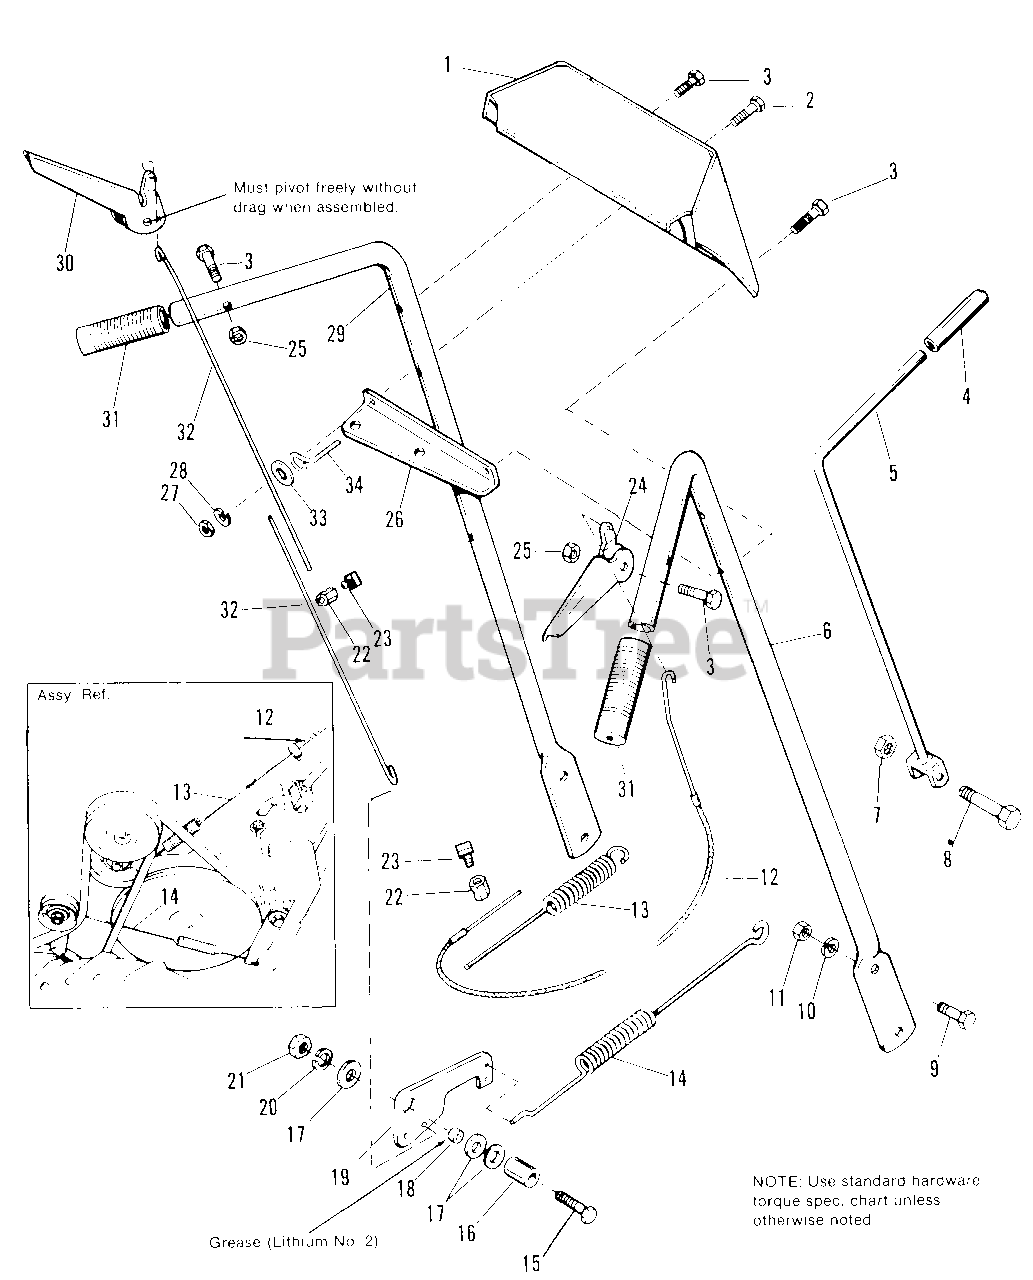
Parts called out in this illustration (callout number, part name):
1	HOUSING ASSY.
2	CAPSCREW, Hex Hd., 1/4-20 x 1-3/4
3	CAPSCREW, Hex Hd., 1/4-20 x 1-1/2
4	GRIP, Handle
5	ROD ASSY., Shift
6	HANDLE, R.H.
7	LOCKNUT, Hex, 5/16-18
8	CAPSCREW, Hex Hd., 5/16-18 x 2
9	CAPSCREW, Hex Hd., 5/16-18 x 7/8
10	LOCKWASHER, 5/16
11	NUT, Hex, Full, 5/16-18
12	CABLE & WIRE ASSY.
14	SPRING, Pivot Arm
15	CAPSCREW, Hex Hd., 7/16-14 x 2-3/4
17	WASHER, Plain, 3/8
19	ARM, Pivot
20	LOCKWASHER, 7/16
21	NUT, Hex, Full, 7/16-14
22	CLAMP, Wire
23	SETSCREW, #10-24 x 5/8
24	GRIP, Clutch, R.H.
25	LOCKNUT, Hex, 1/4-20
26	GUIDE, Rod
27	NUT, Hex, Full, 1/4-20
28	LOCKWASHER, 1/4
29	HANDLE, L.H.
30	GRIP, Clutch, L.H.
32	WIRE, Control
33	WASHER, Plain, 1/4
34	STOP, Belt
